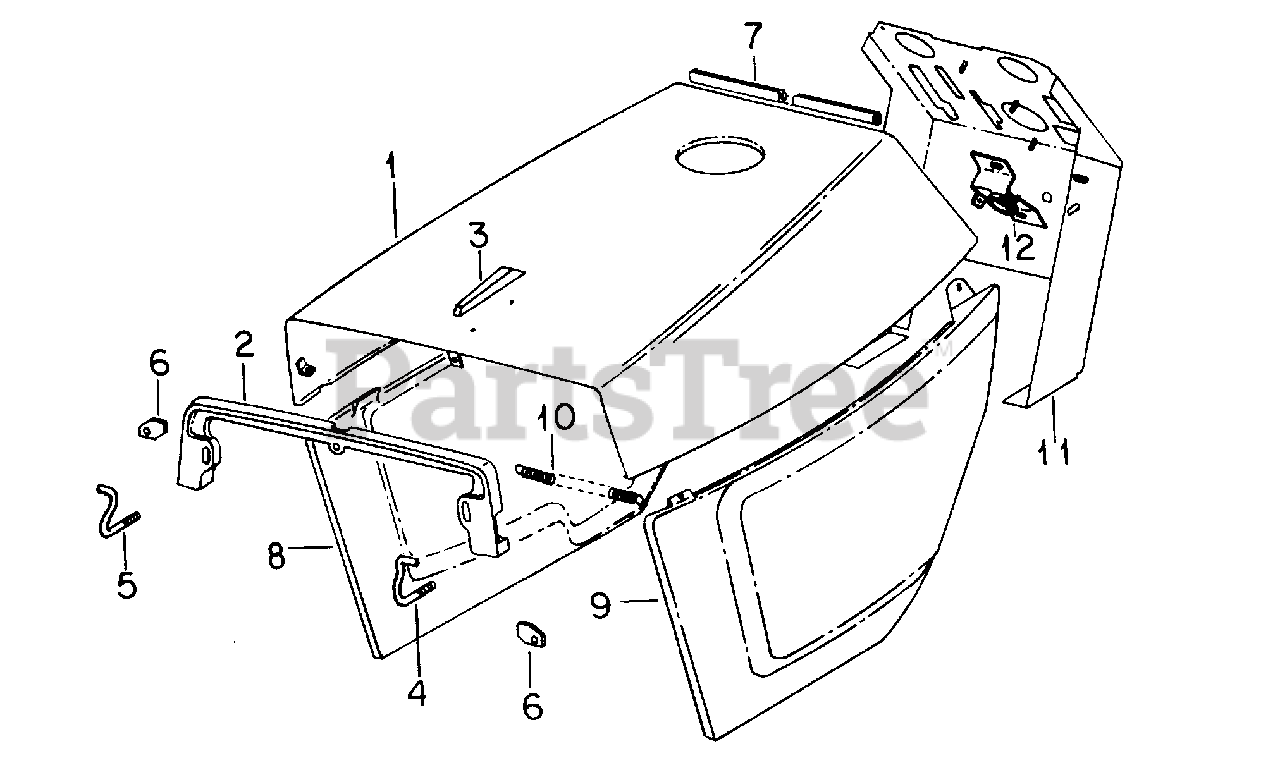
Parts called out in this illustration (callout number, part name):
1	Hood Assy
2	Support, Hood
3	Ornament, Hood
4	Hinge, LH Hood
5	Hinge, RH Hood
6	Plate, Hood Hinge
7	Seal, Edge
10	Spring, Side Panel
11	Pedestal Assy
12	Support Assy, Steering Column
